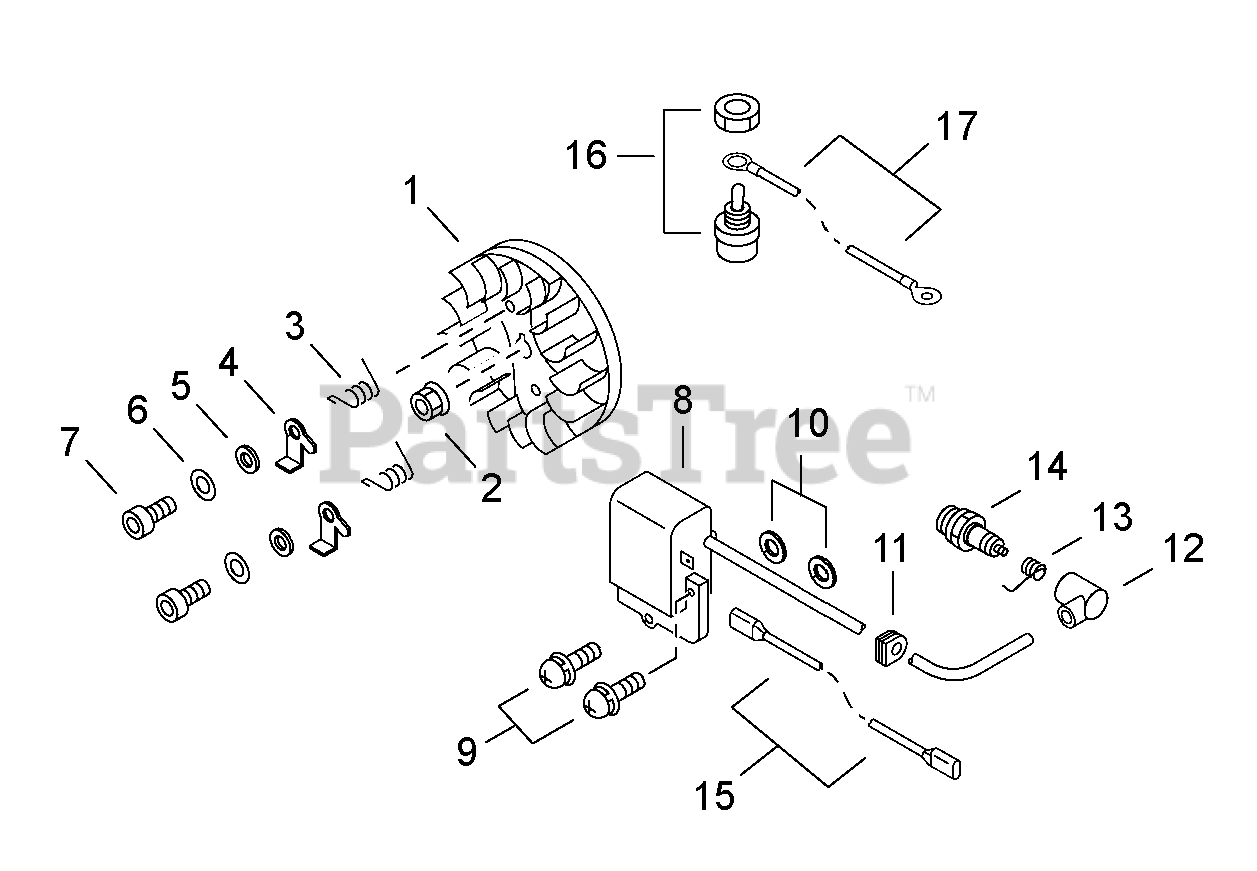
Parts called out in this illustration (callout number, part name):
1	FLYWHEEL
2	NUT, FLANGE M8
3	SPRING, TORSION
4	PAWL, STARTER
5	SPACER 5.2×8×2.1
6	WASHER 5.5×12×0.8
7	BOLT 5×14
8	COIL, IGNITION
9	SCREW 5×22
10	WASHER 5.2×12×3
12	CAP, SPARK PLUG
13	TERMINAL, SPARK PLUG
14	SPARK PLUG - BPM7A
15	LEAD - IGNITION L= 95
16	SWITCH, ON-OFF
17	LEAD - GROUND L= 100
